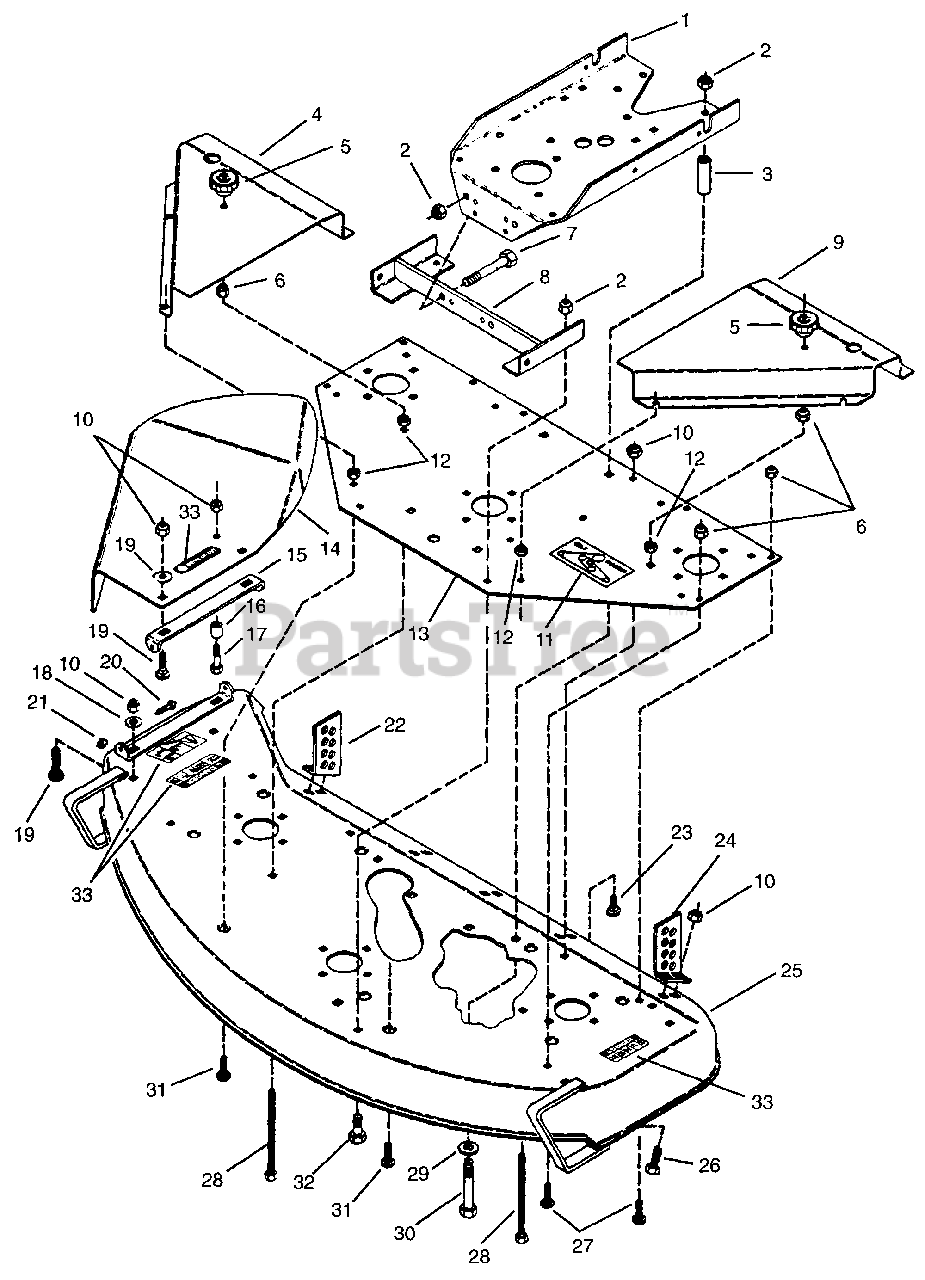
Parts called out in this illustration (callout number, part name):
1	Support, Gear Housing
2	Nut-Locking-Nylon .50-13 Grade 5
3	Spacer .510 x .840 x 2.437
4	Cover, Pulley Right Hand
5	Knob
6	Nut-Locking-Nylon .312-18 Grade 2
7	Bolt-Hex .50-13 x 1.375
8	Bracket, Height Adjustment
9	Cover, Pulley Left Hand
10	Nut-Locking-Nylon .375-16 Grade 2
11	Decal, Belt Installation
12	Nut-Jam .312-18
13	Plate, Support
14	Shield, Safety External 50" Mower
15	Bracket, Chute
16	Bushing-Sleeve .407 x .625 x .750
17	Bolt-Hex .38-16 x 1.50 Grade 5
18	Washer-Flat-Steel .406 x .812 x .065
19	Bolt-Round Head Square Neck .38-16 x 1.0
20	Bolt-Hex .25-20 x .875
21	Nut-Locking-Nylon .250-20 Grade 2
22	Plate, Rear Adjustment
23	Bolt-Round Head Square Neck .375-16 x .75 Grade 1
24	Plate, Rear Adjustment
25	Weldment, 50" Mower Deck
26	Bolt-Hex .38-16 x 1.25 Grade 5
27	Bolt-Round Head Square Neck .31-18 x .75 Grade 5
28	Bolt-Round Head Square Neck .31-18 x 3.5
29	Washer-Flat-Steel .531 x 1.062 x .095
30	Bolt-Hex .50-13 x 3.75
31	Bolt-Round Head Square Neck .31-18 x 1.0
32	Bolt-Hex .50-13 x 1.25 Grade 5
33	Mower Deck Decal
